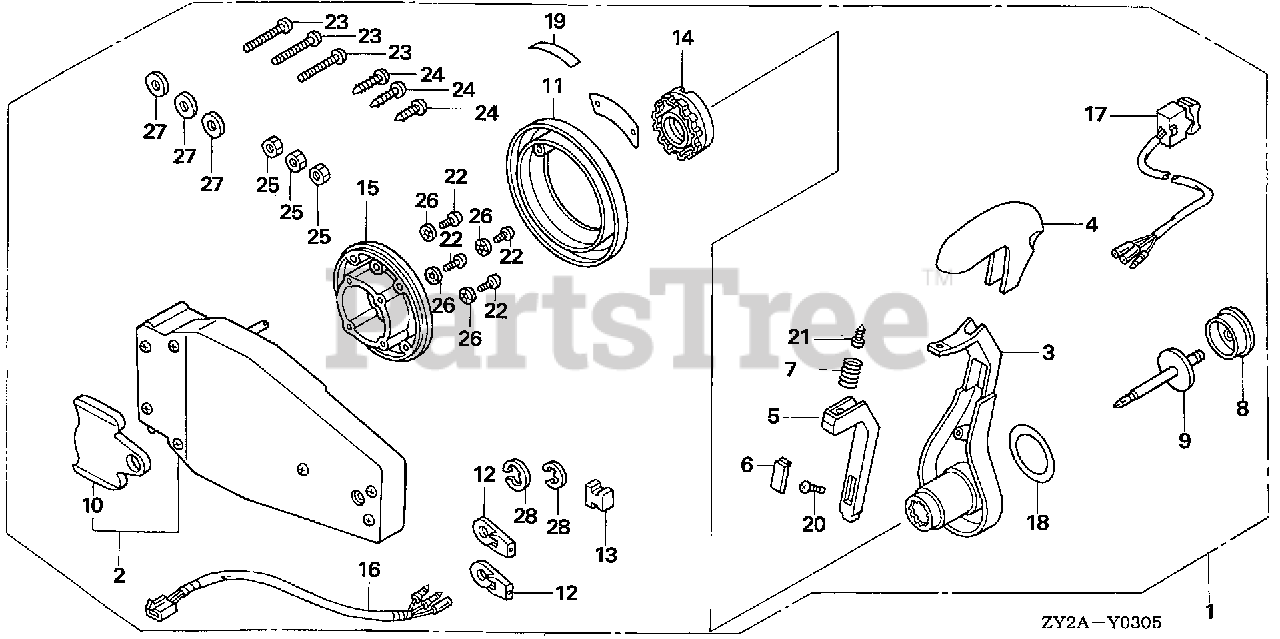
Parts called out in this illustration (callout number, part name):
1	BOX KIT, REMOTE CONTROL (FLUSH MOUNT)(L)
2	HOUSING ASSY., L. (INNER) (FLUSH MOUNT)
3	HANDLE, REMOTE CONTROL
4	COVER, GRIP
5	ARM, NEUTRAL LOCK
6	COVER, LOCK ARM
7	SPRING, NEUTRAL LOCK ARM
8	BUTTON, THROTTLE
9	SHAFT, THROTTLE BUTTON
10	PLATE, DWELL
11	COVER ASSY.
12	TERMINAL, CABLE
13	SPACER, CABLE CLAMP
14	HOLDER, NEUTRAL LOCK
15	BASE
16	SUB-HARNESS ASSY., POWER TRIM-TILT (C)
17	SWITCH ASSY., POWER TRIM-TILT (C)
18	MARK, HANDLE FLUSH MOUNT
19	MARK, FLUSH MOUNT
20	SCREW, TRUSS (4X12)
21	SCREW, PAN (5X10)
22	SCREW, PAN (5X30)
23	SCREW, PAN (6X35)
24	SCREW, TAPPING (6X30)
25	NUT, HEX. (6MM)
26	WASHER, LOCK (5MM)
27	WASHER, PLAIN (6MM)
28	E-RING (6MM)
